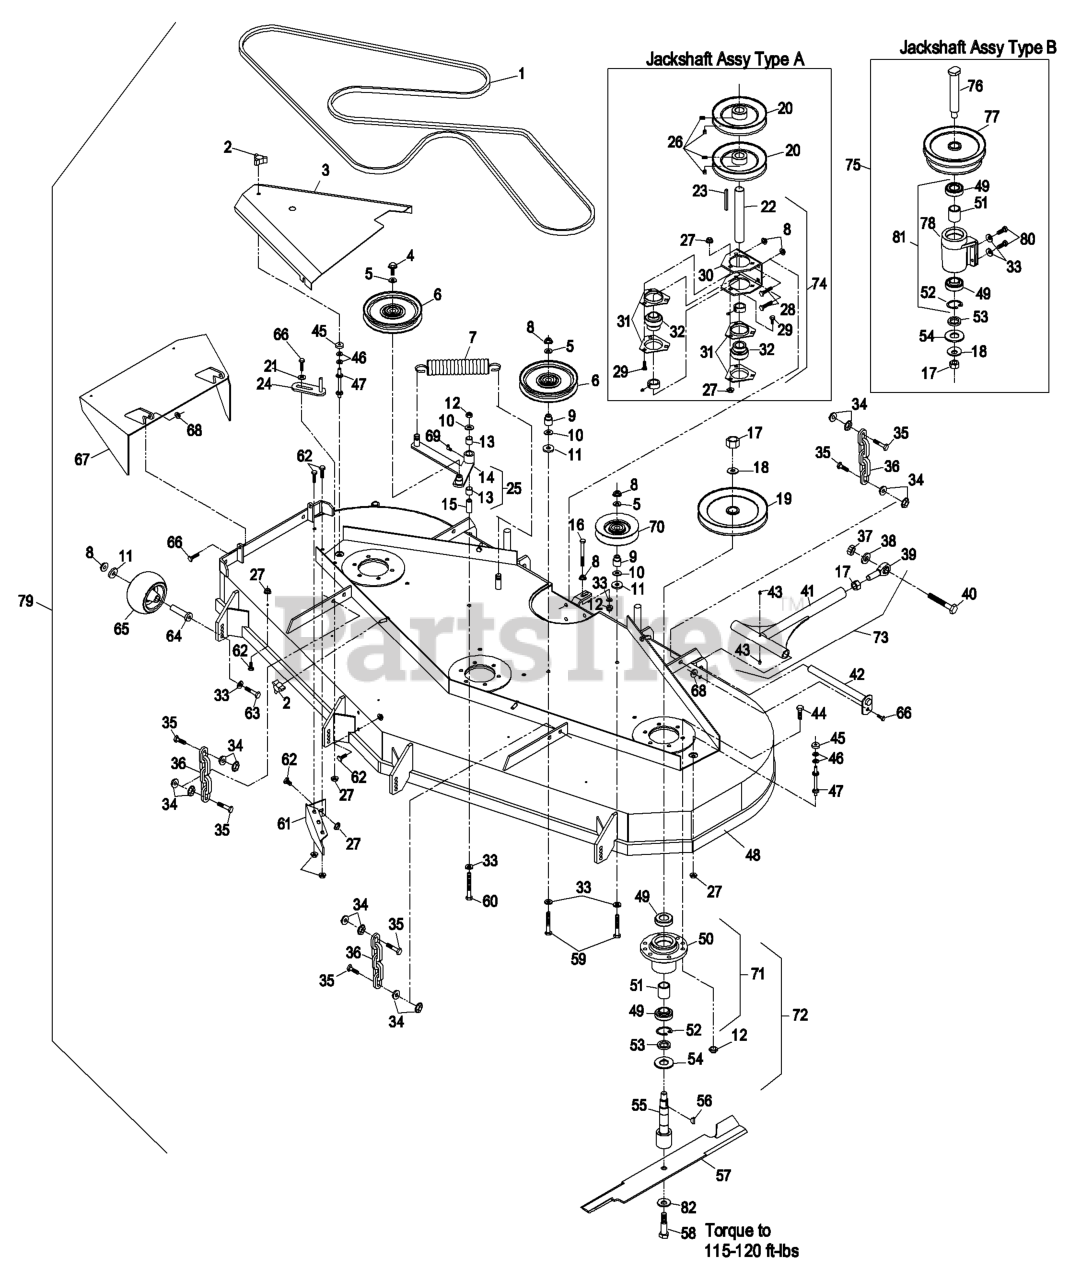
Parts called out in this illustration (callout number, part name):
1	BELT-V
2	KNOB-3 PRONG
3	SHIELD,BELT RH
4	SCREW-HHF
5	WASHER-FLAT
8	NUT-HHF, WHIZ
9	BUSHING-IDLER
10	WASHER-FLAT
12	NUT-LOCK, NI
13	SLEEVE-BEARING
15	BUSHING
16	SCREW-HH
17	NUT-HEX
18	WASHER-SPRING
19	SHEAVE,BLADE DRIVE7.5EOD
20	SHEAVE-SPLIT
21	WASHER-SPRING
22	JACKSHAFT,DECK DRIVE
23	KEY,MACH 1/4X1/4X2-5/8
24	GUIDE-BELT
26	SCREW-SET
27	NUT-HF
28	SCREW-CARR
29	BOLT-CARR
30	BRACKET,JACKSHAFT
31	HOUSING-FLANGE
32	BEARING,W/COLLAR
33	WASHER-BELLEVILLE
35	SCREW-CAP, HH
36	CHAIN-LIFT, DECK
37	NUT-HEX
38	WASHER-LOCK
39	BALLJOINT-SPHERICAL
40	SCREW-HH
42	PIN-STRUT
43	FITTING-GREASE
44	SCREW-HH
46	WASHER-FLAT
47	STUD-SHIELD, BELT (SHORT)
49	BEARING
51	SPACER-BEARING
52	RING-SNAP
53	SPACER-PULLEY/BEARING
54	GUARD-BEARING, BOTTOM
56	KEY-WOODRUFF
58	SCREW-CAP
59	SCREW-HH
60	SCREW-HH
61	WLD,BAFFLE DISCHARGE
62	SCREW-HH
63	SCREW-HH
64	BUSHING-ROLLER
65	ROLLER-SCALP, ANTI
66	SCREW-HH
67	WLD,CHUTE 72
68	Nut, 5/16-18 Nyloc
69	FITTING-GREASE, 90 DEG
70	PULLEY-IDLER
72	SPINDLE HSG ASSYCOMP72
73	ASM,STRUT SHORT
74	DK DR. BRG. ASSY
75	ASM,J-SHFTKIT60,72 3750
76	JACKSHAFT
77	SHEAVE,JACKSHAFT-DOUBLE
79	Complete Deck Assembly
80	SCREW-HH
82	WASHER-BLADE BOLT, HEAVY
